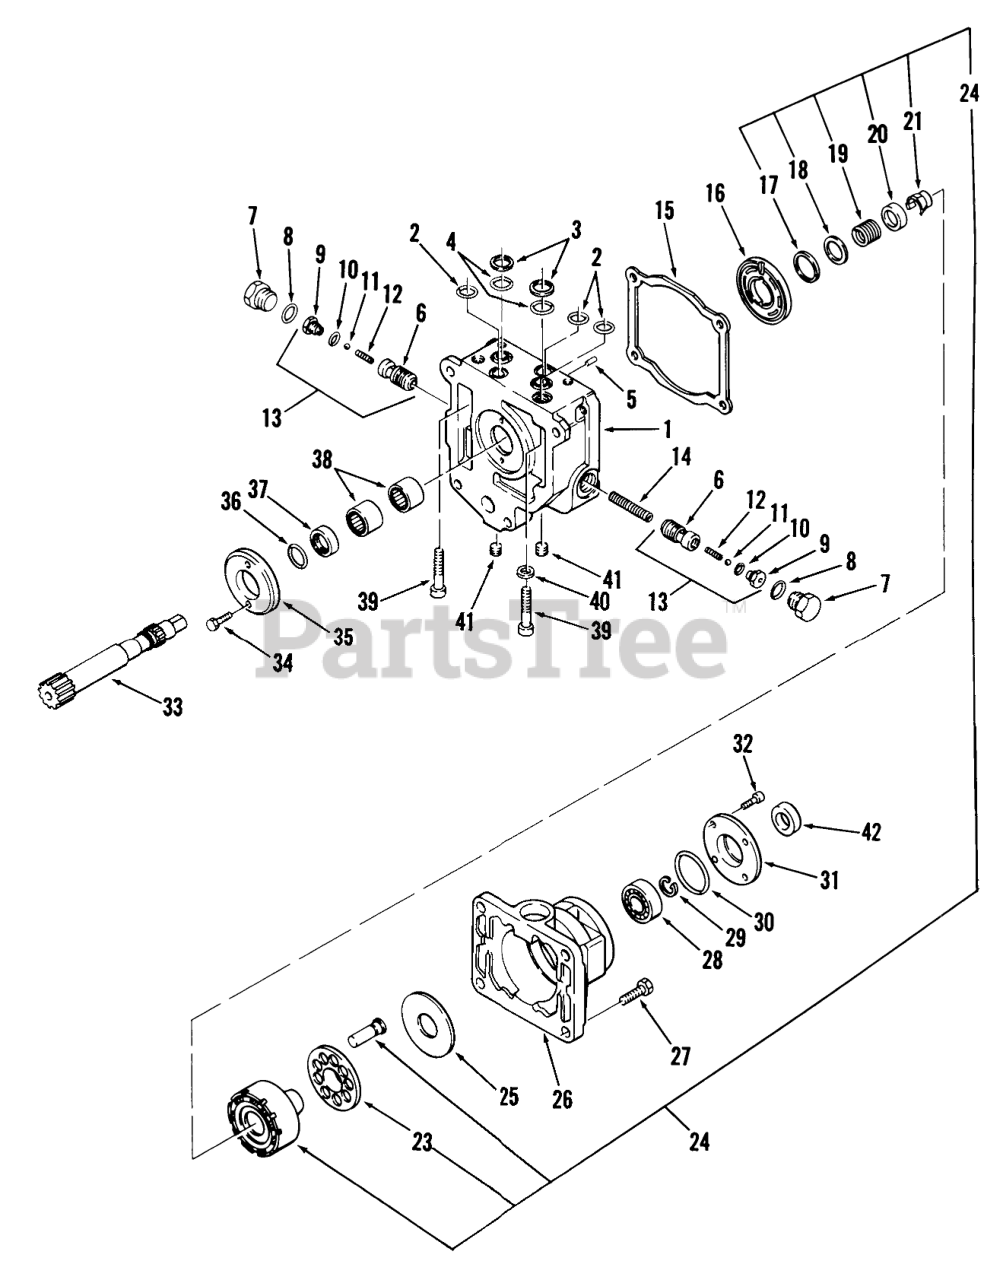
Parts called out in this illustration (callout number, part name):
1	End Cap-Motor
2	O RING
3	RING BACKUP
4	O RING
5	Locating Pin
6	Sleeve
8	O-RING
9	Valve
10	O-Ring
12	SPRING
13	Sleeve
14	Spring
15	Gasket-Motor
16	Valve Plate
17	RING-SUN9006250-0112
18	WASHER-9009625-0018
19	Spring
20	SEAT-SUND 3102407
21	Retaining Clip
23	RETAINER-SUN 3100194
24	Cyl Blk Kit Inc 17-23
25	Thrust Plate
26	Motor Housing
27	Hex Head Cap Screw
28	BALL BRG9001305-0004
29	SNAP RING
30	O-RING
31	PLATE-COVER
32	Cap Screw
33	Motor Shaft
34	Cap Screw
36	O-RING--9004175-0001
37	Bellcrank Assembly
38	Needle Bearing
39	Socket HD Cap Screw
40	Copper Washer
41	Pipe Plug
